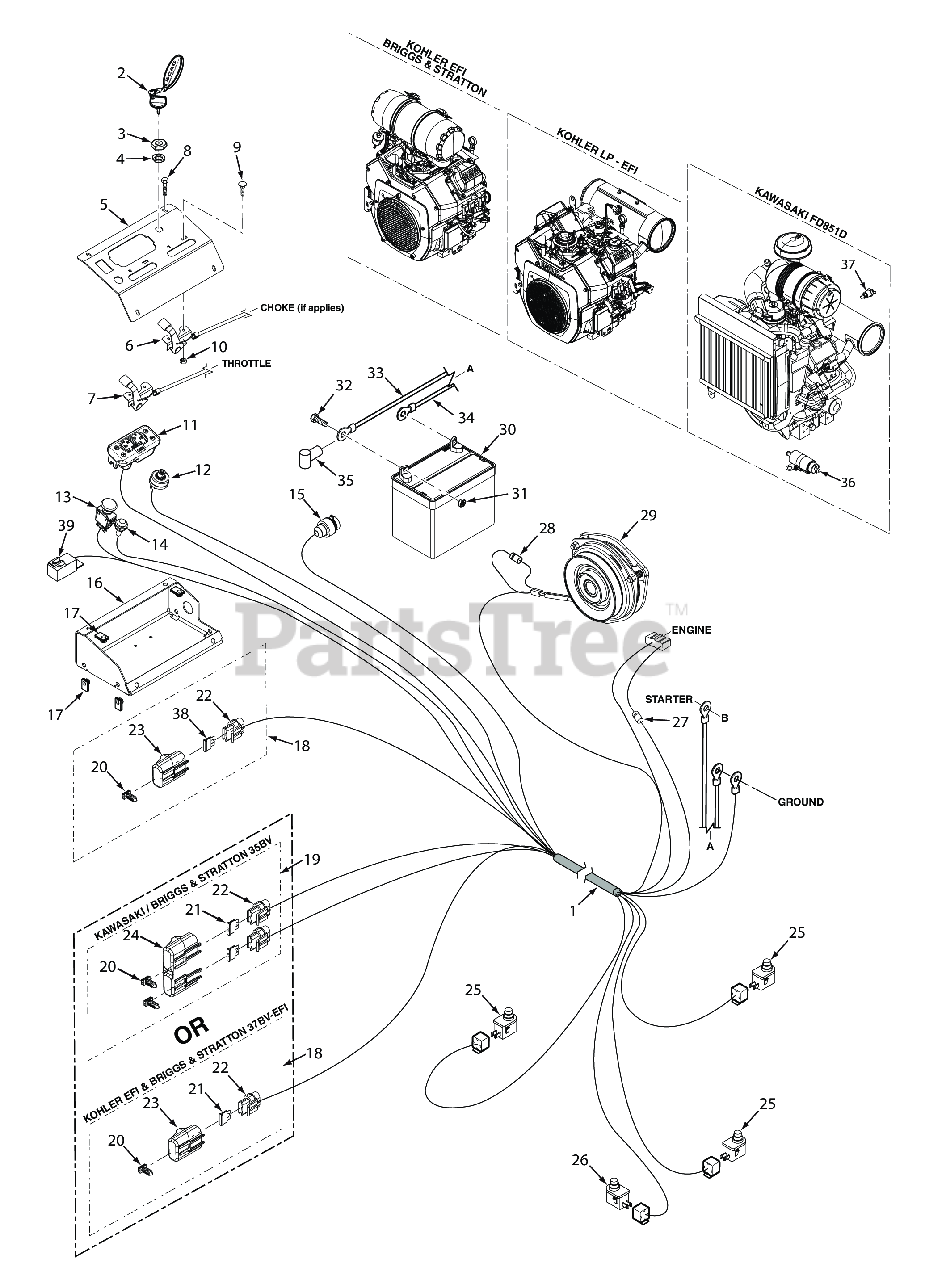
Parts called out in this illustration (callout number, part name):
1	Wire Harness, STTII-BV (Briggs & Stratton)
1	Wire Harness, STTII-BV-EFI (Briggs & Stratton)
1	Wire Harness, STTII-EFI (Kohler EFI, Gasoline & LP)
1	Wire Harness, STTII-FD851D DFI (Kawasaki)
2	Key, Assembly w/Fob
3	Nut, 5/8-32 Special
4	LOCK WASHER, 5/8" INTERNAL TOOTH
5	Instrument Panel w/Decal
6	Control Cable (Kawasaki FX921 Throttle & Choke Cable)
7	Control Cable (Briggs & Stratton)
7	Control Cable, Throttle (35BV)
8	Bolt, Hex Head Serrated Flange 1/4-20 x 3/4"
9	Bolt, Carriage #10-24 x 1/2"
10	Nut, Elastic Stop #10-24
11	Tiger Eye, Cluster Gauge
12	KEY SWITCH(INCLUDES MOUNTING HARDWARE)
13	Switch, PTO - 10 Amp
14	Indicator Light, Glow Plugs (Includes Mounting Hardware)
15	Power Plug, 12V
16	Base, Instrument Panel
17	Bolt, Hex Head 3/8-16 x 1"
18	Single Fuse Assy., Excluding Fuse
19	Double Fuse Assy.
20	Clip, Fuse Holder
21	FUSE, 20 AMP BLADE TYPE AUTOMOTIVE
22	Fuse Holder Assembly
23	Cover, Sealed Single
24	Cover, Sealed Double
25	Switch, Interlock, Normally Open
26	Plunger Switch, Single Pole
27	Decal, Forward Speed Selector
28	Diode, 600V 6 Amp
29	Electric Clutch w/Tag - GT-3.5 (FX850)
29	Electric Clutch w/Tag - GT-5 (ECV860, ECV940)
30	Battery, 350 CCA
31	Nut, 1/4 - 20 Hex
32	Bolt, Hex Head 1/4-20 x .5" Battery, (Not Available Through Scag)
33	Battery Cable, 44" Red w/Braid (26EFI) - Kohler
33	Battery Cable, 18" Red w/Braid (25KA, 26DFI, 31DFI) - Kawasaki
33	Battery Cable, 50" Red w/Braid (35BV & 37BV-EFI) - Briggs & Stratton
34	Battery Cable, 39" Black (26EFI) - Kohler
34	Battery Cable, 31-1/2" Black (25KA, 26DFI, 31DFI) - Kawasaki
34	Battery Cable, 27" Black (35BV & 37BV-EFI) - Briggs & Stratton
35	RUBBER BOOT
36	Fuel Pump
37	Sender Unit, Water Temp. (Liquid Cooled Only)
38	Fuse, 5 Amp
39	Relay, 12V 40 AMP Standard
